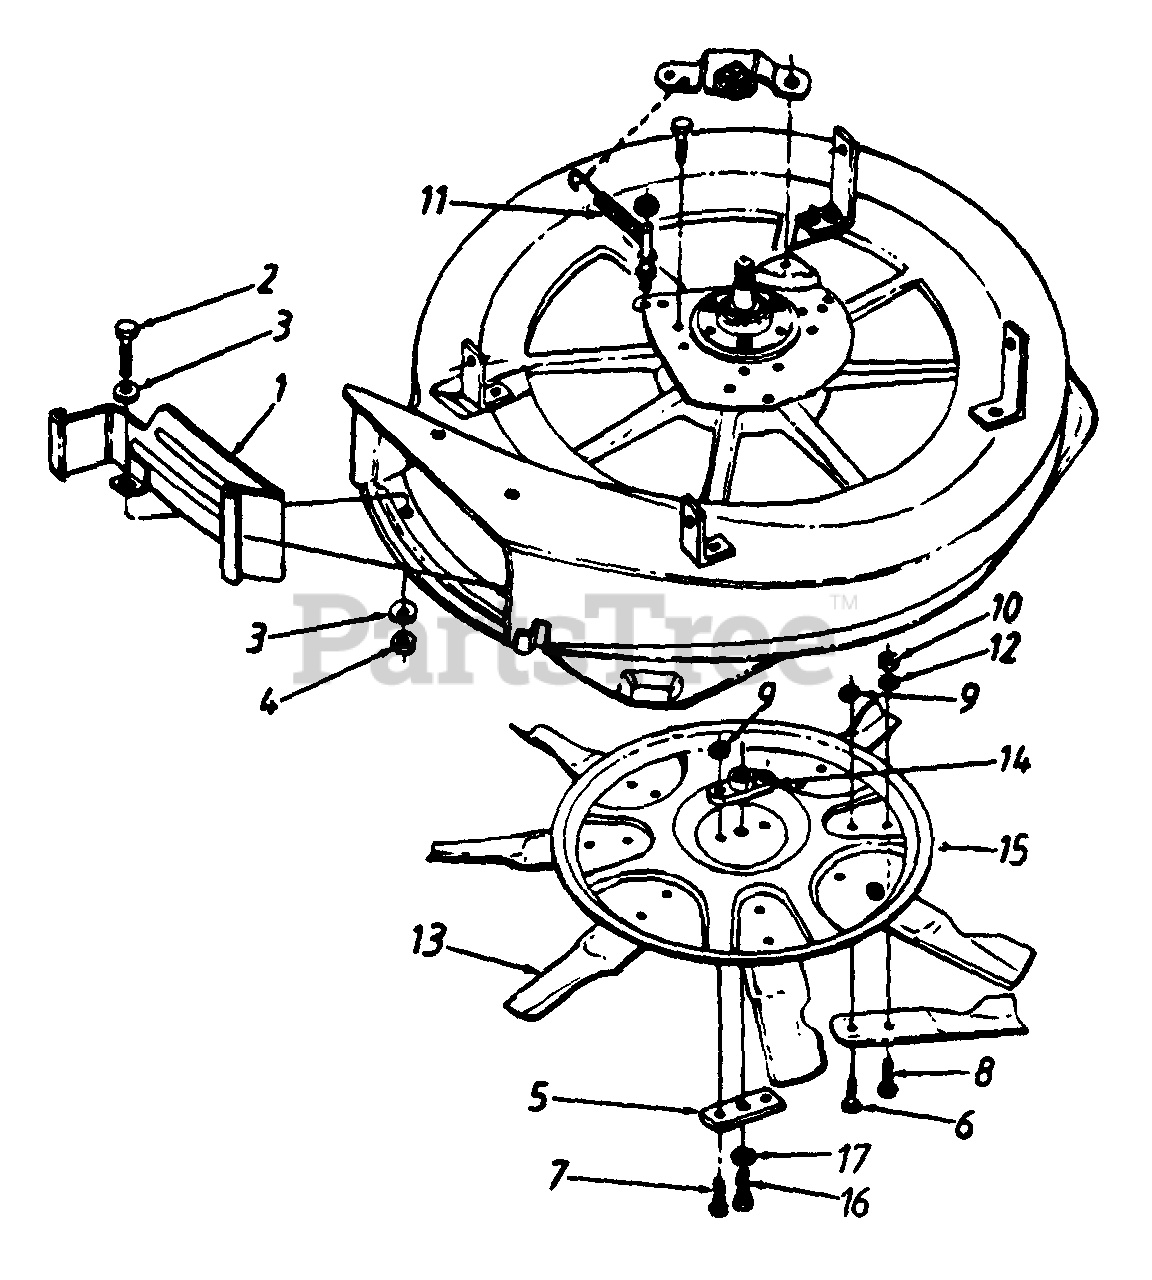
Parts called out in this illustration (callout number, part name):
1	Mulching Baffle Ass'y.
2	Hex Bolt 5/16-18 x .5"
3	Bell-Wash. .325" I.D.
4	Hex L-Nut 5/16-18 Thd.
7	Hex Bolt 5/16-24 x 1.25" Lg. (Gr. 5)
8	Hex Bolt 3/8-24 x .88" Lg.
9	Hex L-Nut 5/16-24 Thd.
10	Hex L-Nut 3/8-24 Thd. (Gr. 5)
11	Extension Spring 3.2" Lg.
12	Fl-Wash. .406" I.D. x .75"
13	30" Mulching Blade Tip
14	Blade Adapter
15	30" Mulching Blade Disc
16	Hex Bolt 3/8-24 x 1.25" Lg. (Gr. 8)
17	L-Wash. 3/8" I.D.
